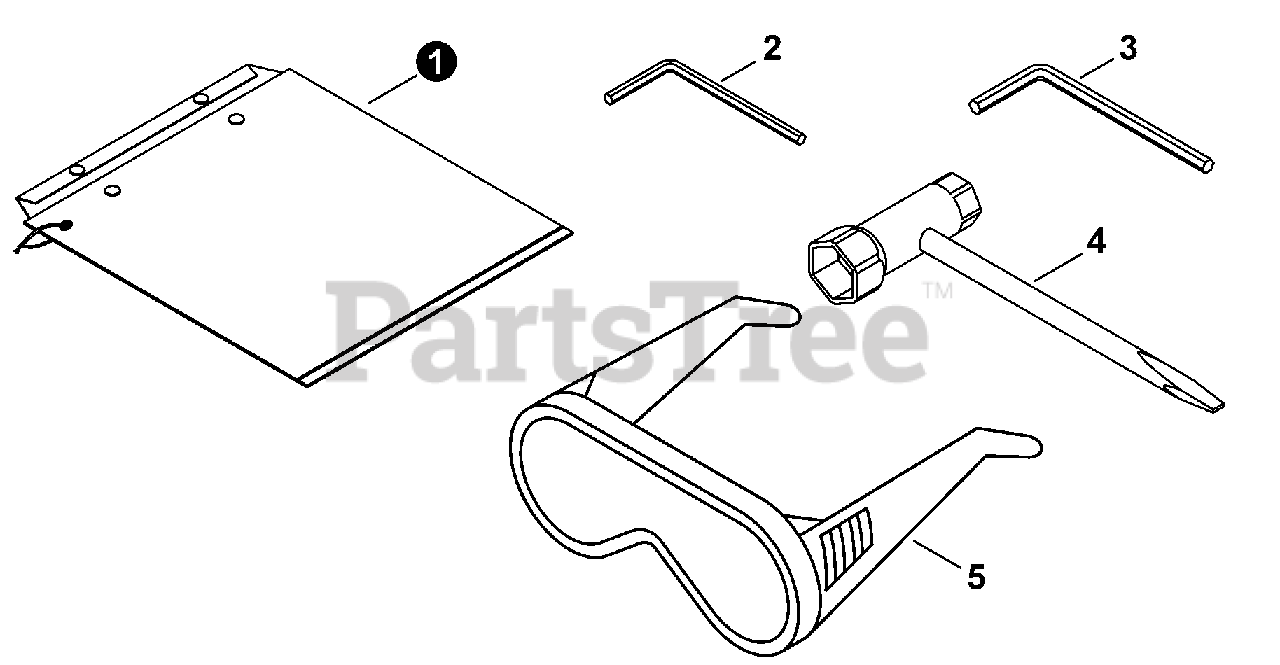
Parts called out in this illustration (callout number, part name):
1	BAG, TOOL
2	WRENCH, ALLEN 4MM
3	WRENCH, ALLEN 5MM
4	T-WRENCH 17×19mm
5	GLASSES, SAFETY
